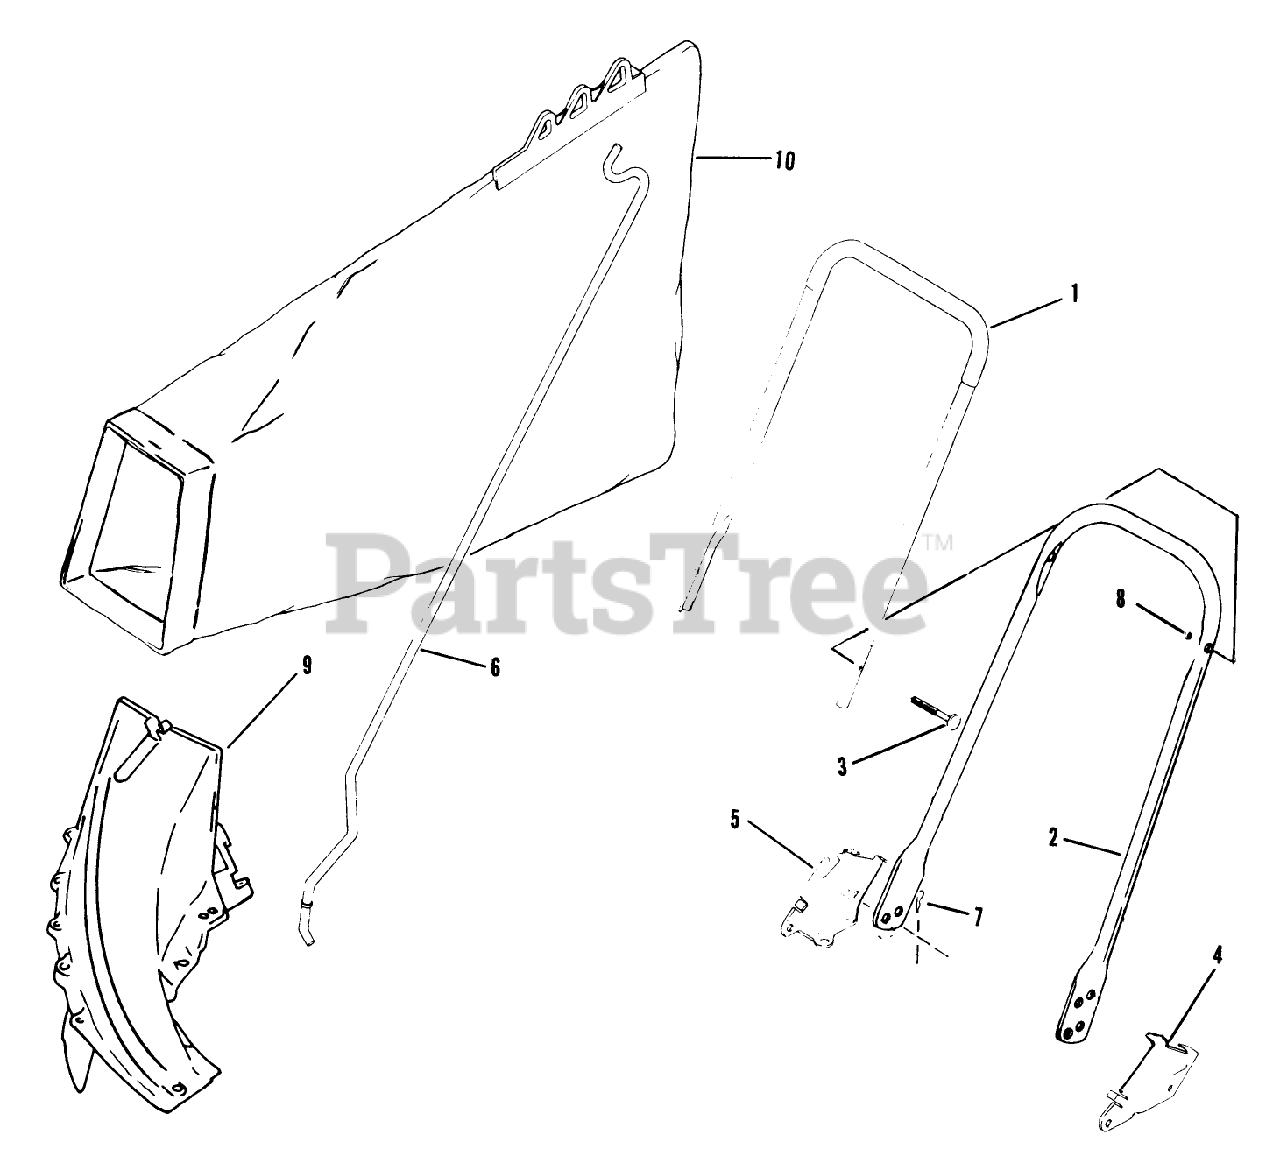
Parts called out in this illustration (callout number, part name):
7	HAIR PIN
8	LOCKNUT E
10	89802 LB WHOLE GOODS
